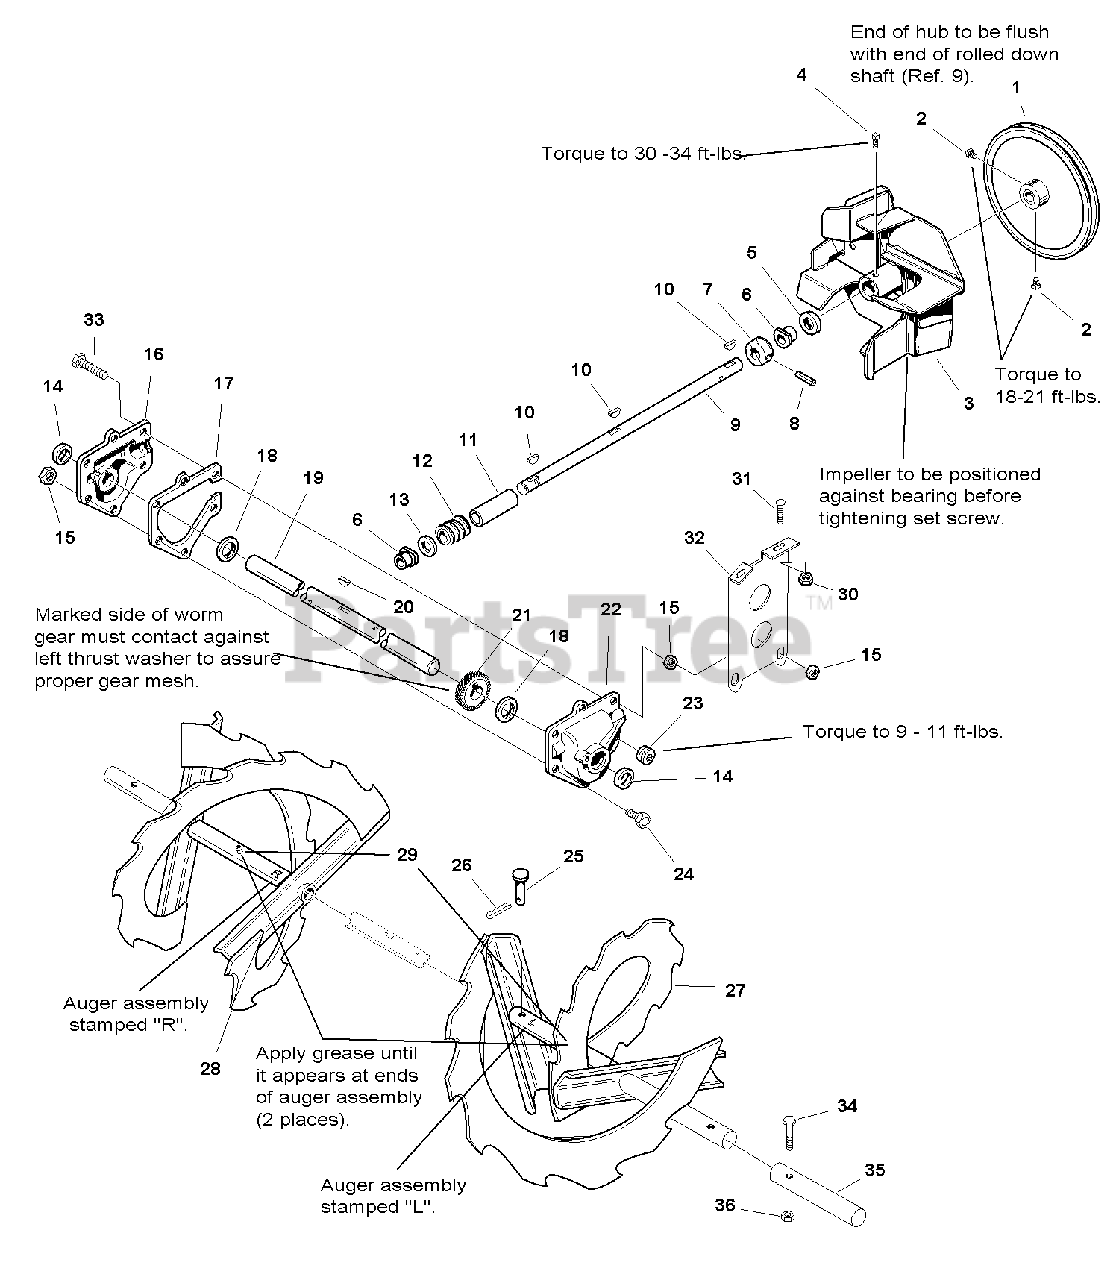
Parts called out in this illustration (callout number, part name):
1	PULLEY, Auger Input
2	SETSCREW, Square Head, 5/16-18 x 1/2
3	IMPELLER ASSEMBLY
4	SETSCREW, Square Head, 3/8-16x 1/2
6	BUSHING, Flange
7	COLLAR, Thrust
8	PIN, Drivelok, 3/16 x 1-1/2
9	SHAFT, Worm
10	KEY, Woodruff, 3/16 x 5/8
12	GEAR, Rolled Worm
13	WASHER, Thrust
15	LOCKNUT, Hex, 1/4-20
16	CASE, Gear, RH
18	WASHER, Thrust
19	SHAFT, Auger
20	KEY, Woodruff, 1/4 x 3/4
21	GEAR, Worm
22	CASE, Gear, LH
23	PLUG, Pipe, Tapered, 1/8
24	CAPSCREW, Hex Head, 1/4-20 x 7/8
25	PIN, Shear
26	PIN, Cotter, 3/32 x 3/4
27	AUGER ASSEMBLY, LH, 38"
28	AUGER ASSEMBLY, RH, 38"
29	FITTING, Lube, 1/4
30	NUT, Hex Flange Whiz Lock, 5/16-18
31	CARRIAGE BOLT, 5/16-18 x 3/4
32	SUPPORT, Gear Box
33	CAPSCREW, Hex Head, 1/4-20 x 2-1/2
34	CAPSCREW, Hex Head, 1/4-20 x 1-3/4
36	NUT, 1/4-20
